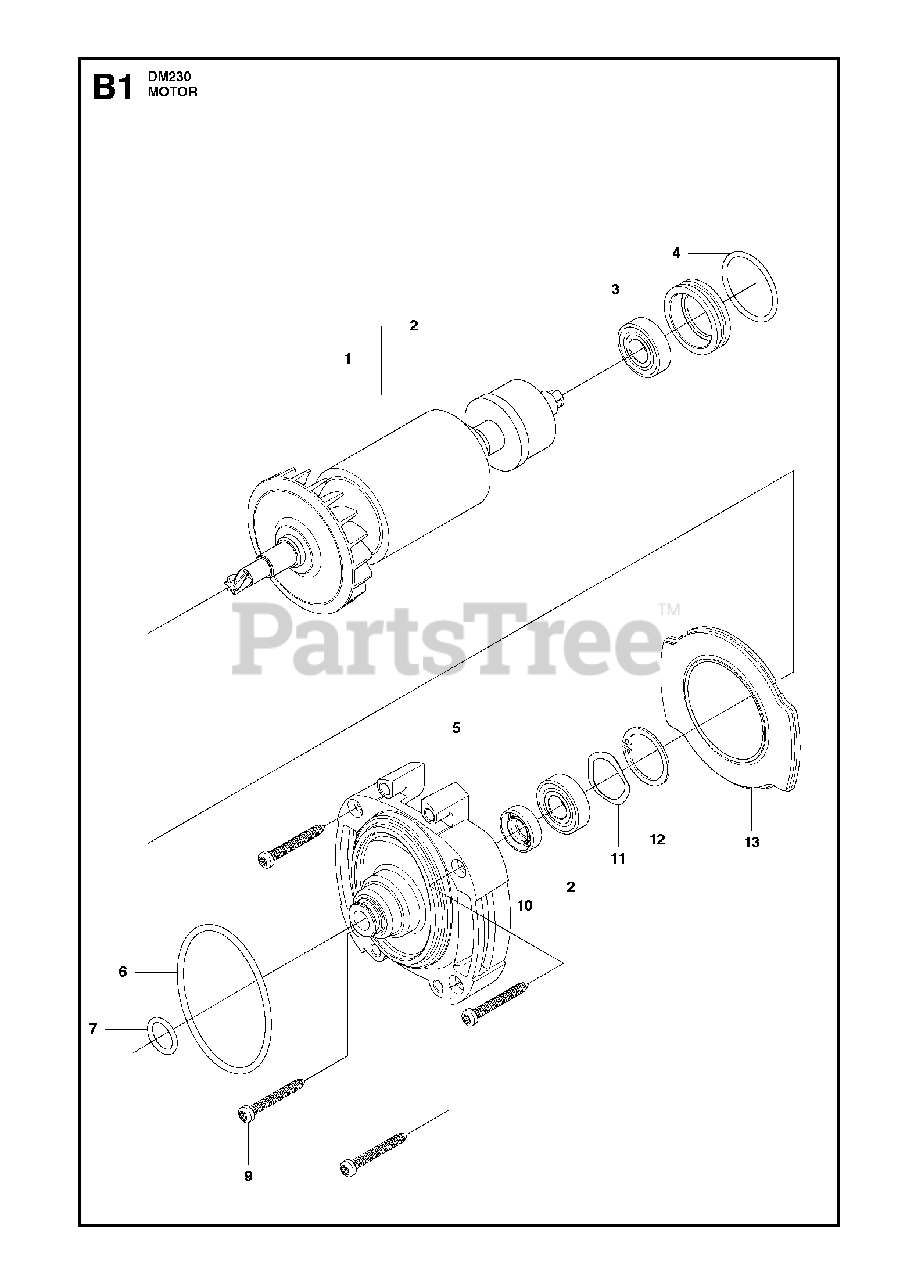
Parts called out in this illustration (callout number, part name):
3	BEARING SUPPORT
10	SEALING
11	SPRING WASHER
